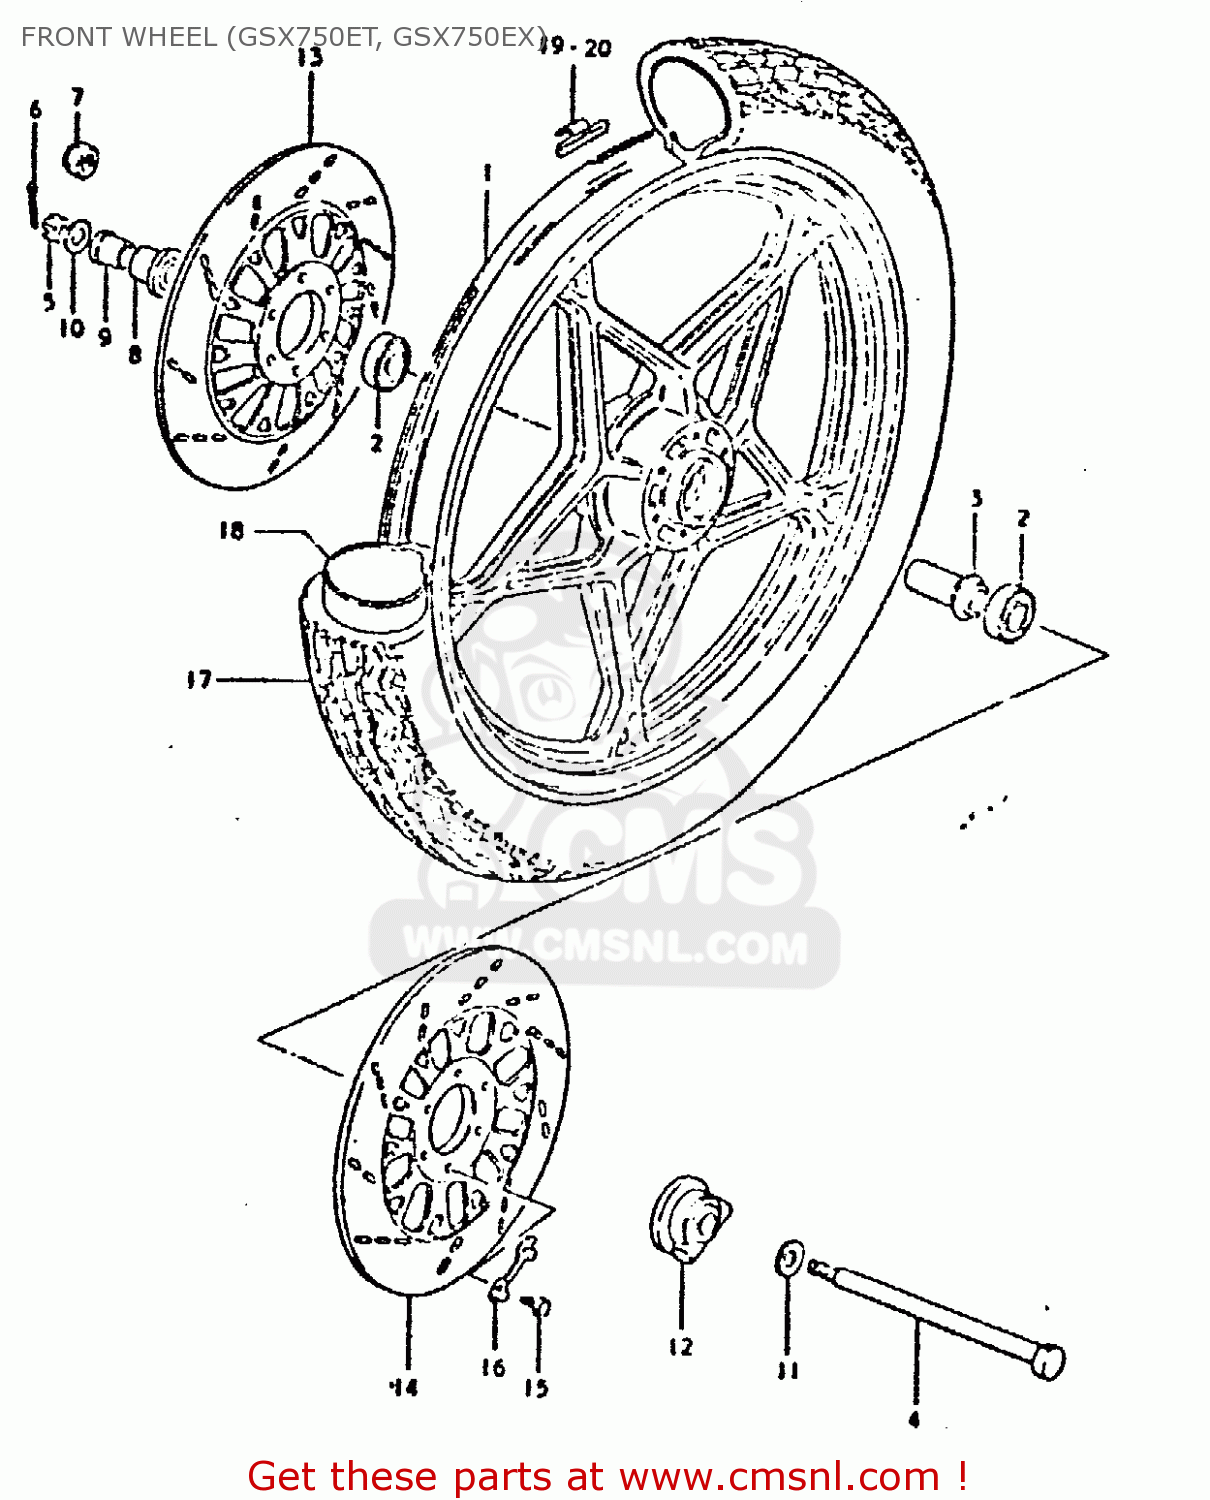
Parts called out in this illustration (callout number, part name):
1	WHEEL, FRONT
2	BEARING
3	SPACER,FR HUB BEARING
4	AXLE,FR
5	NUT 12MM
6	COTTER PIN
8	SPACER,FR AXLE,R
9	SPACER
10	WASHER
11	WASHER(15.5X26X2.3)
12	BOX ASSY,SPEEDOMETER GEAR
13	DISC,FR BRAKE,R
14	DISC,FR BRAKE,L
15	BOLT(8X25)
16	WASHER
17	TIRE,FRONT
18	TUBE,INNER
19	BALANCER,WHEEL
20	BALANCER,WHEEL
